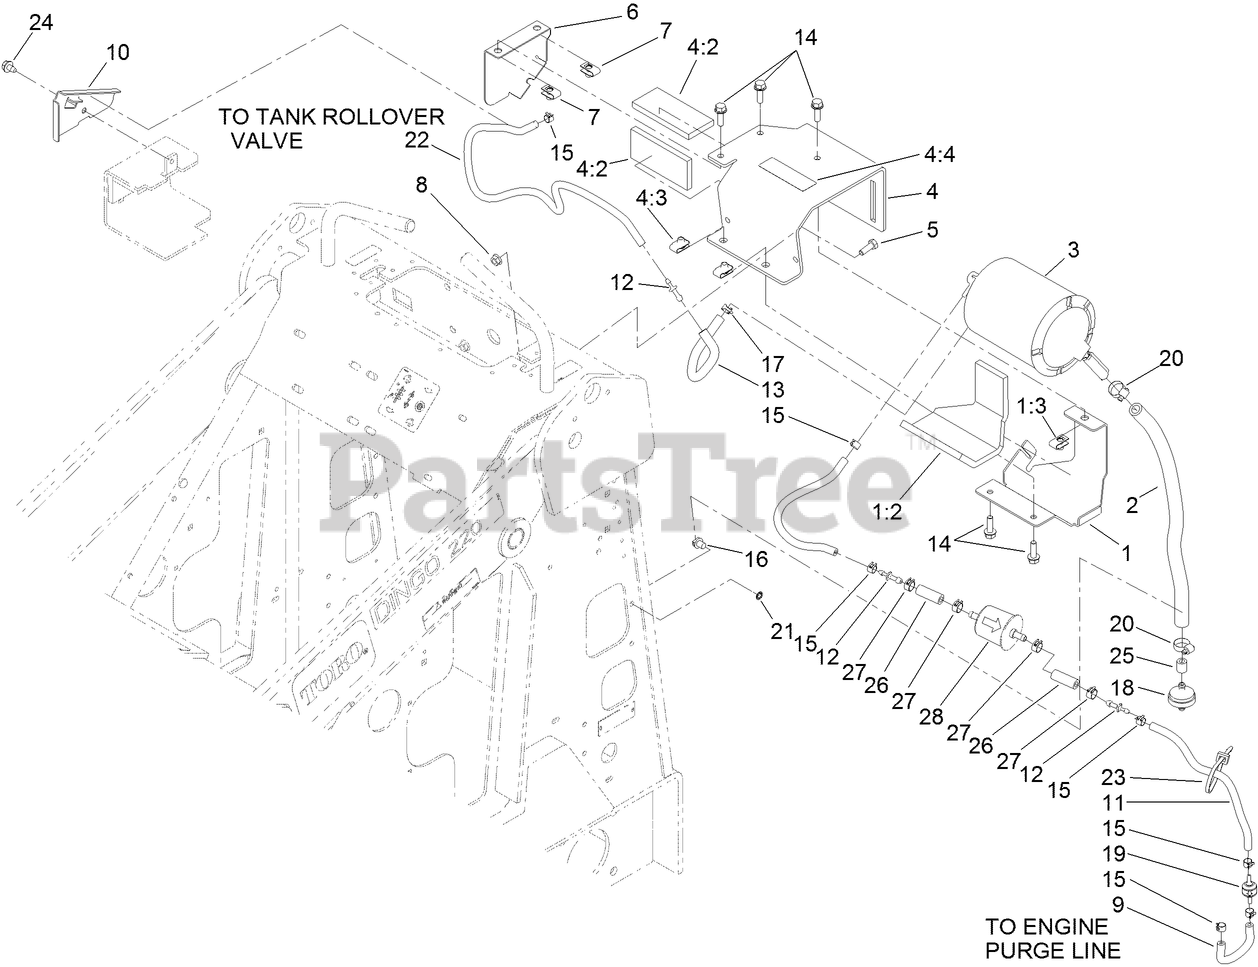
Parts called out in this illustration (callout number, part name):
1	CANISTER MOUNT ASM
1:2	PAD-FOAM
1:3	NUT-CLIP, U
2	HOSE-VENT
3	CANISTER-CARBON, 1200CC
4	CANISTER BRACKET ASM
4:2	PAD-FOAM
4:3	NUT-CLIP, U
4:4	DECAL-MANUAL
5	SCREW-HH
6	COVER-CANISTER
7	NUT-CLIP, U
8	NUT-HF
9	HOSE-FUEL
10	PLATE-HOSE RETAINER, RH
11	HOSE-FUEL
12	FITTING-STRAIGHT
13	Hose-Fuel
14	SCREW-HHF
15	CLAMP-HOSE
16	CLIP-TIE
17	CLAMP-HOSE
18	FILTER-FUEL, INLINE
19	VALVE-CHECK, VACUUM
20	CLAMP-HOSE
21	WASHER-LOCK
22	HOSE-FUEL
23	TIE-CABLE
24	SCREW
25	HOSE-FUEL
26	HOSE-FUEL
27	CLAMP-HOSE
28	FILTER-FUEL
